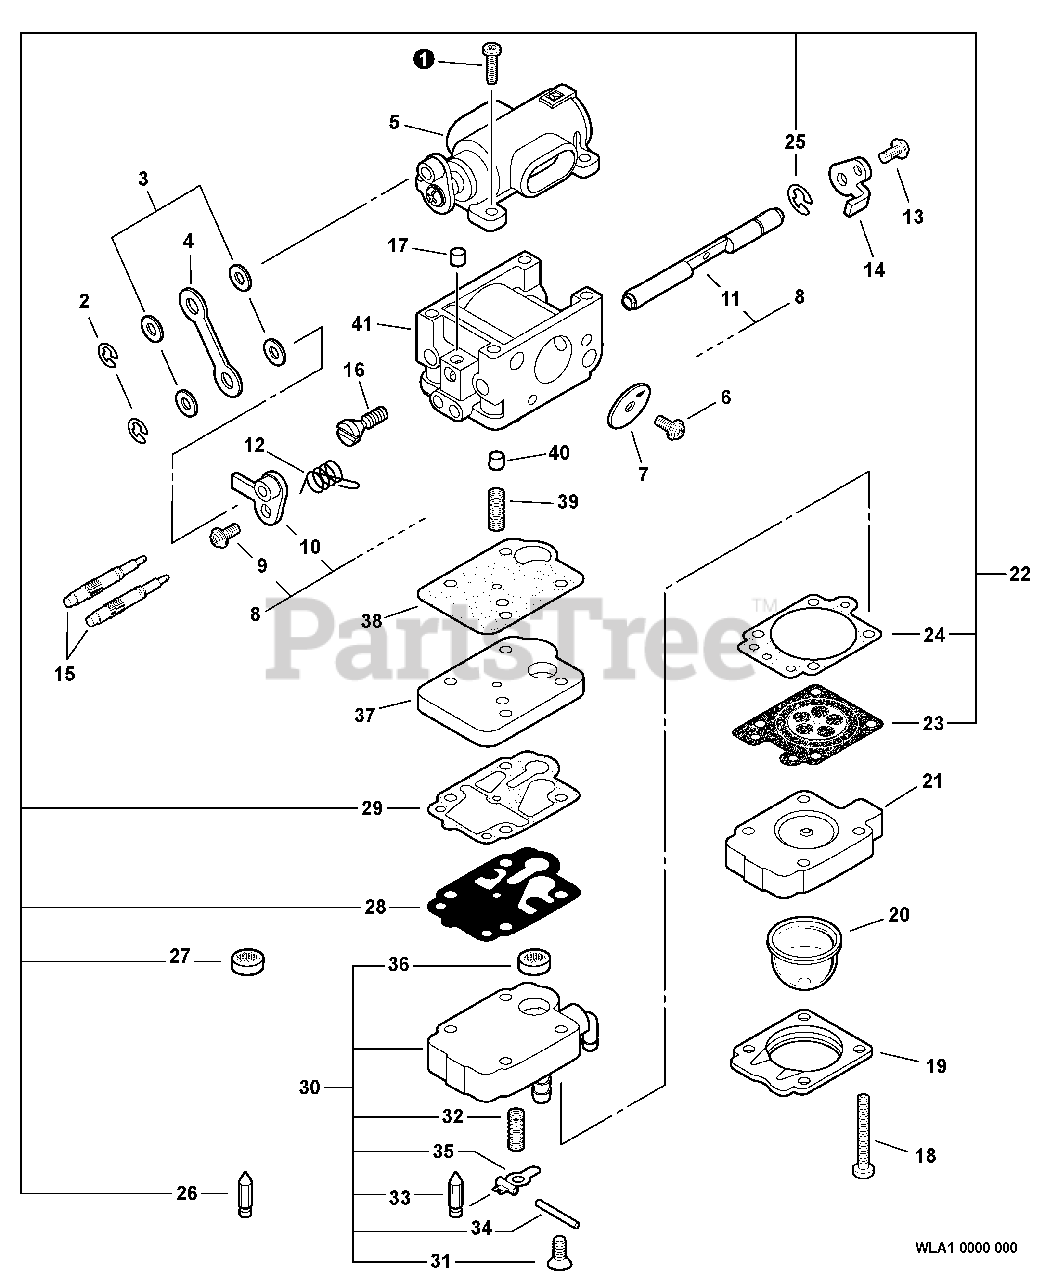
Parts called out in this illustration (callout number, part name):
4	LINK, ROD
5	VALVE ASSY, AIR
7	VALVE, THROTTLE
8	SHAFT ASSY, THROTTLE
10	LINK ASSY, THROTTLE
11	SHAFT, THROTTLE
14	LEVER, CHOKE
15	NEEDLE, MIXTURE
17	PLUG, FRICTION
19	RETAINER, PURGE BULB
20	BULB, PURGE
21	BODY ASSY, PURGE
22	REPAIR KIT
23	DIAPHRAGM, METERING
24	GASKET, METERING
25	RING, RETAINING
26	VALVE, INLET NEEDLE
27	STRAINER
28	DIAPHRAGM, PUMP
29	GASKET, PUMP
30	BODY ASSY, PUMP
32	SPRING, METERING LEVER
33	VALVE, INLET NEEDLE
34	PIN, METERING LEVER
35	LEVER, METERING
36	STRAINER
37	PLATE, PASSAGE
38	GASKET, PASSAGE
40	PISTON ASSY
41	BODY, CARBURETOR
